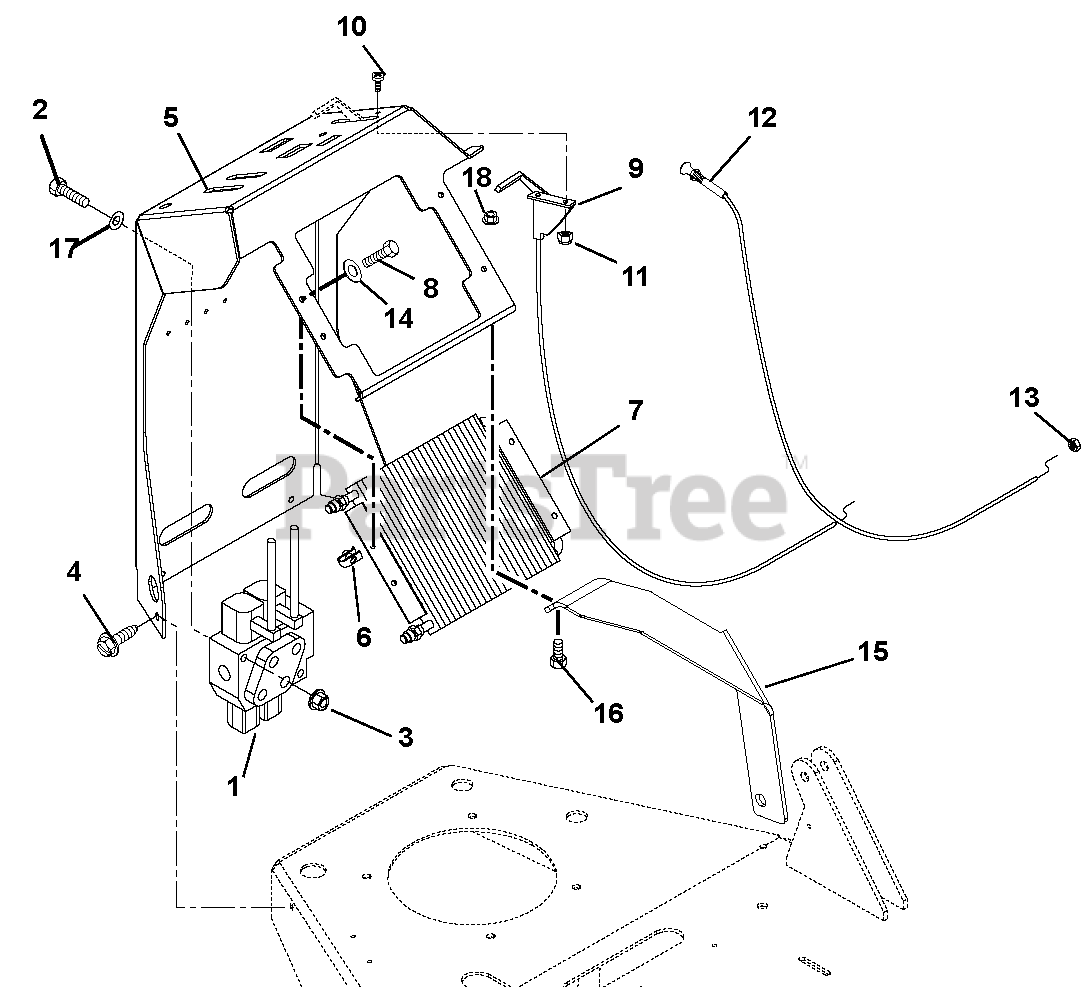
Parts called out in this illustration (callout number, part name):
2	2
3	2
4	4
8	4
10	2
11	2
13	AR
14	4
16	2
17	2
18	2
